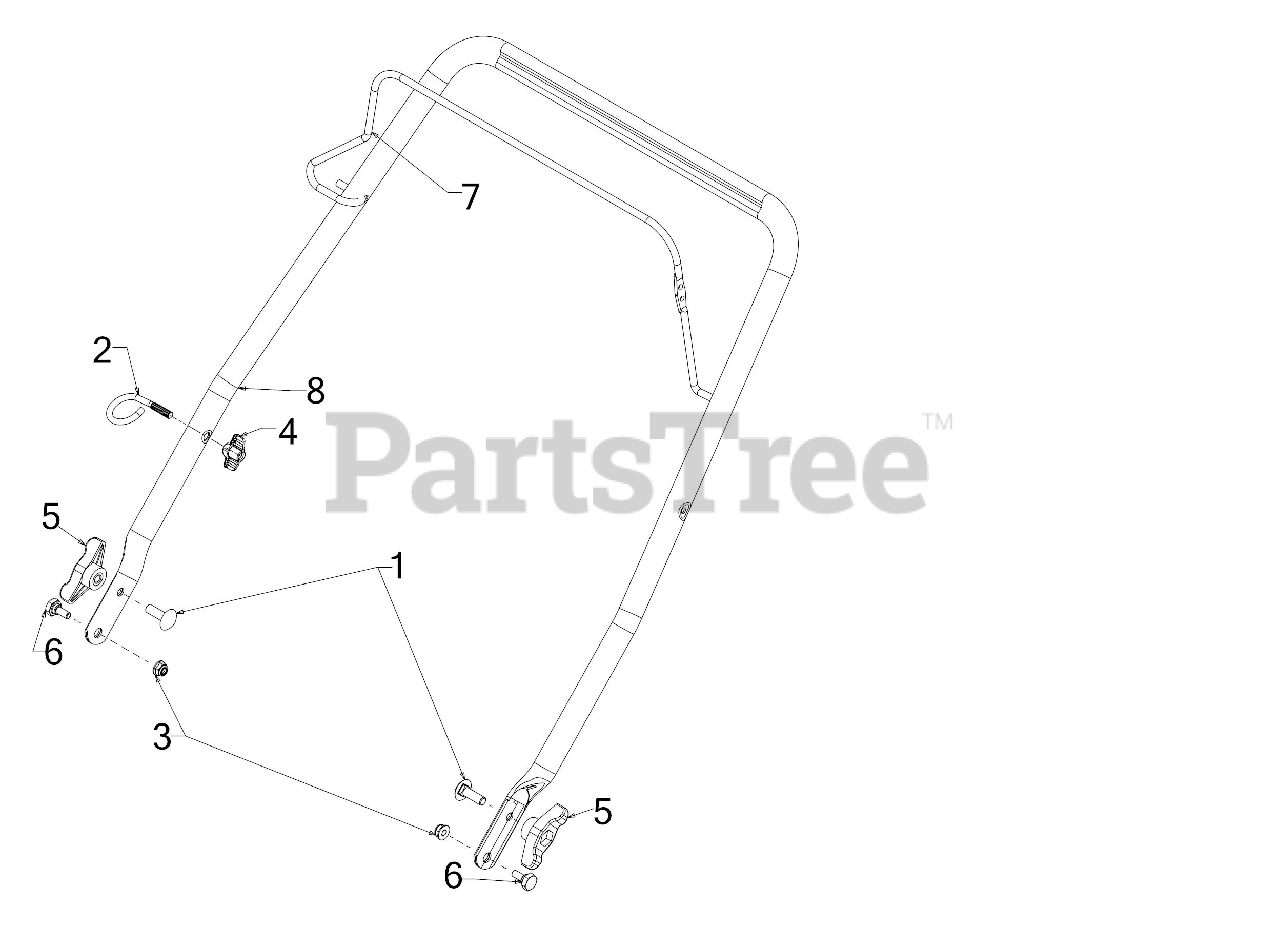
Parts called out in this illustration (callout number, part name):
1	SCREW 5/16-18 x 1.00 GR5
2	EYEBOLT 1/4-20
3	FLANGE LOCK NUT
4	HANDLE KNOB
5	WING KNOB 5/16-18
6	SHOULDER SCREW
7	OPERATOR BAIL
8	UPPER HANDLE
